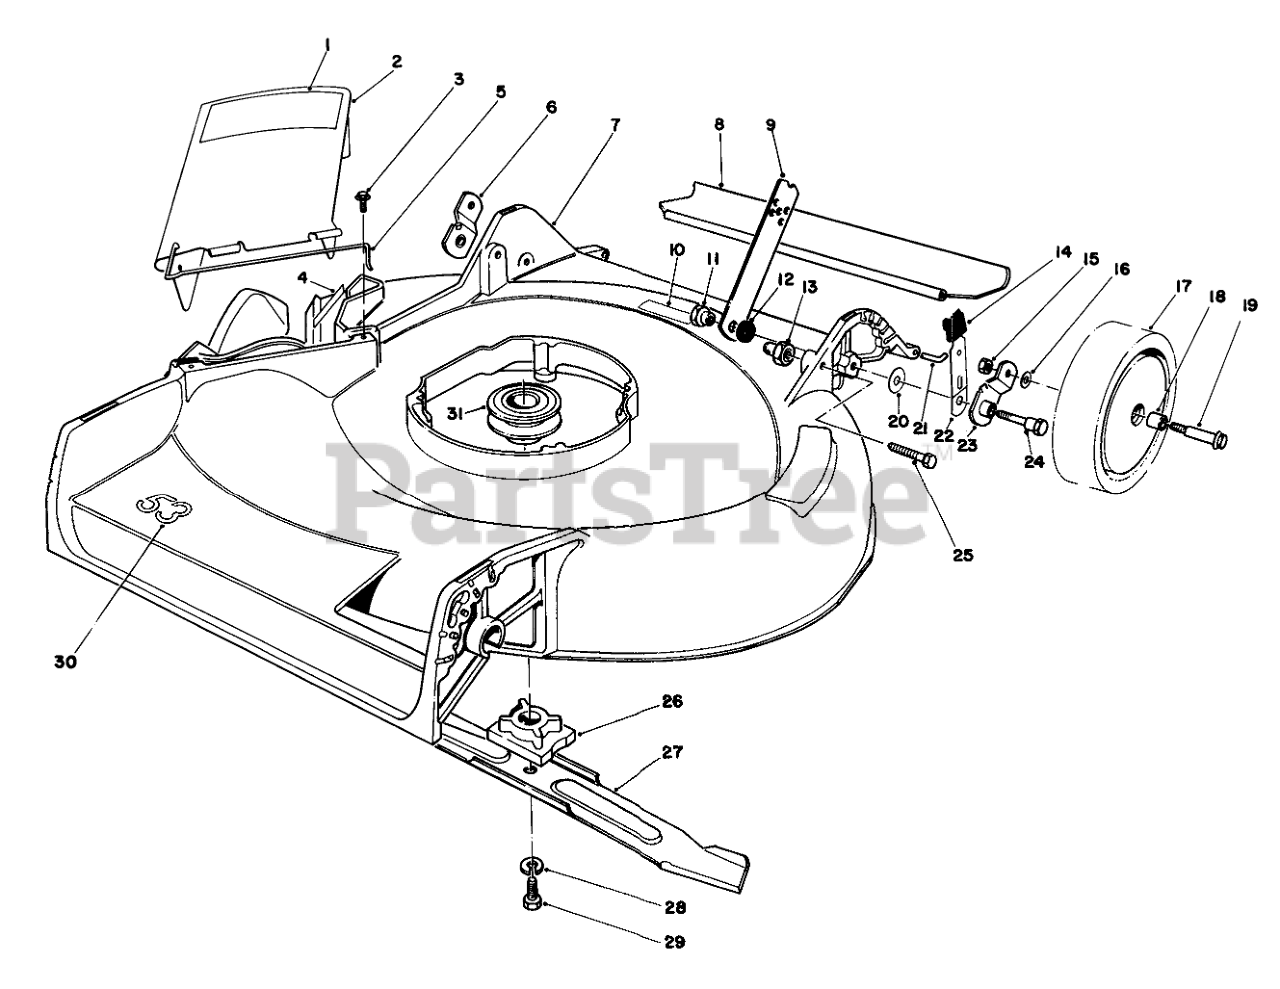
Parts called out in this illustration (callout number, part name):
1	DECAL - DANGER DEFL
2	Deflector(lncl. Ref. #1)
3	SCREW-HWH
4	DANGER DECAL
5	SPRING HINGE
6	Pivot Arm
7	HOUSING/DECAL
8	REAR SAFETY SHIELD 21
9	HANDLE LATCH
10	Decal
11	HANDLE PIVOT NUT
12	SPACER
13	HANDLE PIVOT NUT
14	KNOB-ARM
15	Nut
16	WASHER
17	Wheel 8 Tire Assembly (Incl. Ref. #18)
18	BUSHING
19	BOLT-WHEEL
20	WASHER-PIVOT
21	SHIELD ROD
22	SPRING ARM ASM
23	Pivot Arm
24	PIVOT SCREW
25	SCREW-HH
26	BLADE RETAINER
27	Blade
28	WASHER-LOCK
29	SCREW-HH
30	DECAL - 53
31	PULLEY-DRIVER
